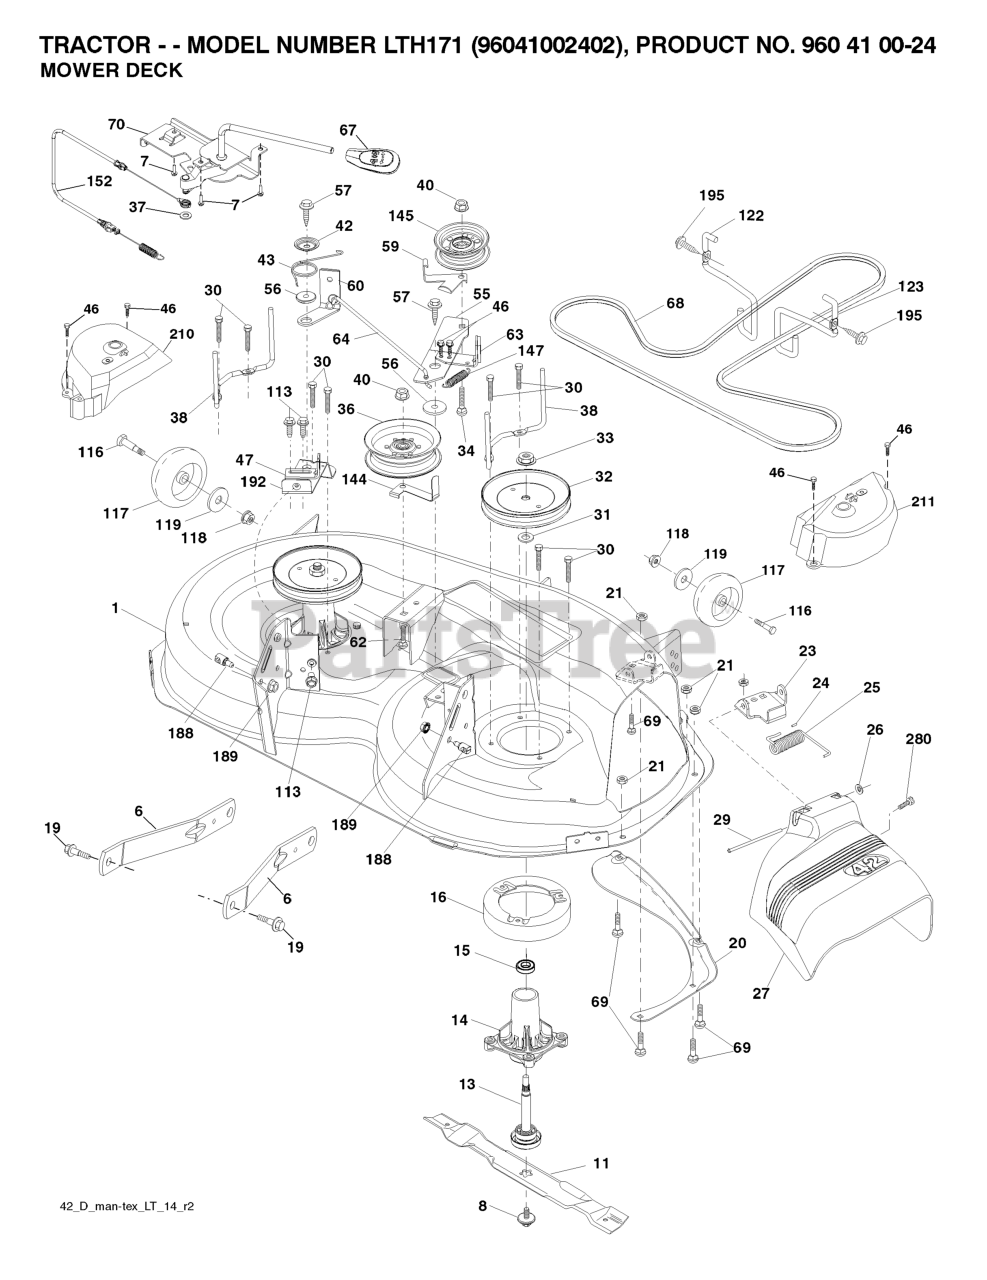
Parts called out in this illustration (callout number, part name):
1	DECK.WELDMENT.42"
6	ARM.SUSPENSION.MOWER.R
7	SCREW
8	BOLT.WASHER.ASM.7/16-2
11	42" HI-LIFT BLADE
13	SHAFT.ASM.MDRL.N/GREASE.38
14	RP.HOUSING.MANDREL.4PT.
16	STRIPPER.MANDREL.ROUND.BLACK
19	BOLT.SHOULDER
20	BAFFLE.VORTEX
21	LOCKNUT
23	BRKT.DEFLECTOR.38"2005+
24	CAP-SLEEVE LT
25	SPRING.TORSION.DEFLECT
26	NUT PUSH M
27	DEFLECTOR ASM.42"TEX.FRENCH
29	ROD.HINGE
30	SCREW, WASHER HEAD
31	WASHER.SPACER.MANDREL
32	PULLEY.MANDREL.5.438.PD
33	NUT.FLANGE.LOCK.TOP
34	BOLT.3/8-16X1.50
36	PULLEY.IDLER.2006
37	WASHER
38	KEEPER.BELT.LH.MANDREL
40	NUT LOCK FLG 3/8-16 UNC
42	SPRING.TORSION.BRAKE
43	SRPING.TORSION.RETAINE
46	SCREW.1/4-20X5/8
47	BRKT.CLUTCH.CABLE
56	SPACER.RETAINER
57	SCREW 3/8-16X1
59	GUARD, BELT
60	ARM BRAKE MOWER
63	ARM BRAKE MOWER
64	LINK BRAKE
67	HANDLE.CLUTCH.CABLE.LT
68	BELT.DRIVE.MOWER.TEX.42"
69	BOLT
70	CLUTCH.ASM.MANUAL.LT.PRED
113	BOLT.5/16HEX.WHS.HD
115	BOLT.CARR.5/16-18X5/8.SHORT
116	BOLT M
117	WHEEL.GAGE.HALF.SPOKED
118	LOCKNUT
119	WASHER.5/16.FLAT.STE.STD.
122	KEEPER BELT ENGINE LH
123	KEEPER BELT RH
144	KEEPER.BELT.MOWER
145	PULLEY.IDLER.48"PRIMARY
147	RETURN SPRING
152	CLUTCH CABLE
188	STUD.FASTNER.W/ANTI-ROTATE
189	NUT LOCK HEX FLANGE 5/16-18
192	BRKT.BRAKE.STAND.LH.
195	SCREW, 3/8-16X3/4
280	SCREW 3/8-16X1/2
